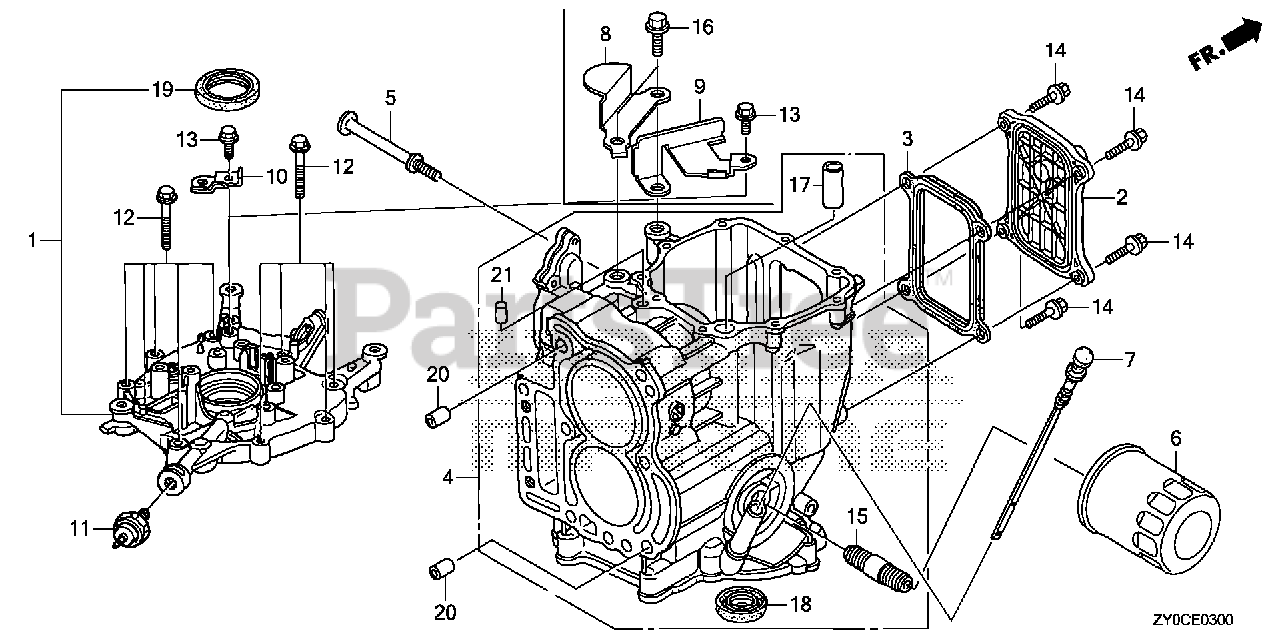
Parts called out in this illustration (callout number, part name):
1	COVER ASSY., CRANKCASE (800)
2	COVER, CRANKCASE SIDE
3	GASKET, CRANKCASE SIDE COVER
4	BLOCK ASSY., CYLINDER (000) *NH8* (DARK GRAY)
5	STOPPER, ENGINE SIDE
6	FILTER, OIL (TOYO ROKI)
6	FILTER, OIL (DENSO)
7	DIPSTICK, OIL
10	BRACKET, CLIP B
11	SWITCH ASSY., OIL PRESSURE
12	BOLT, FLANGE (6X28)
13	BOLT, FLANGE (6X14) (CT200)
14	BOLT, FLANGE (6X22) (CT200)
15	HOLDER, OIL FILTER
17	PIN, DOWEL (14X20)
18	OIL SEAL (28X45X8)
19	OIL SEAL (35X50X8) (NOK)
20	PIN, DOWEL (10X12)
21	PIN B, DOWEL (8X14)
